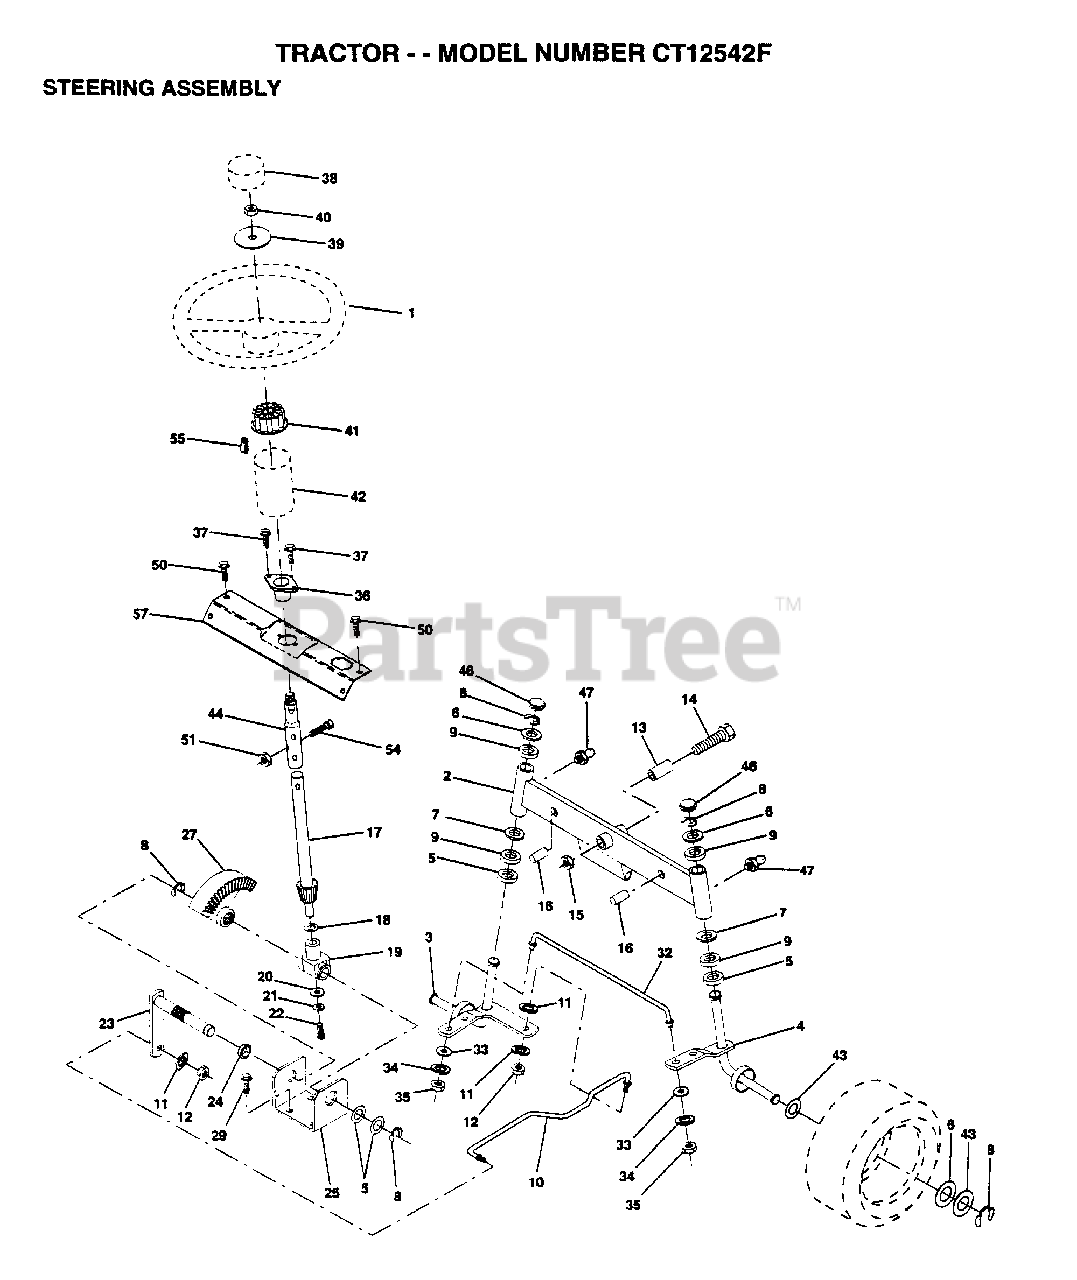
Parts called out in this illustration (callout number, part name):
1	WHEEL STR AYP BLK
2	AXLE ASM FRONT
3	SPINDLE LH
4	SPINDLE RH
5	WASHER .T
6	WASHER
7	WASHER
8	RING
9	COL. SRTG. BEAR.
11	LOCKWASHER
13	BEARING
14	BOLT HEX 5/8-11
15	"NUT-LOC,FLANGE LT"
16	AXLE PIN
17	SHAFT ASM STEERIN
18	THRUST WASHER
19	SUPPORT.SHAFT
21	LOCKWASHER
22	"SCREW,SPECIAL"
24	NYLINER T
25	"BRKT,STEERING"
27	GEAR SECTOR
29	SCREW
32	ROD.TIE.19.75
33	WASHER M
34	LOCKWASHER
35	NUT.LOCK.5/16-24
38	CAP STEER AYP
39	WASHER T
40	GRIPCO NUT
41	ADAPTER-WHEEL LT
42	BOOT SHAFT STEER
43	WASHER
44	SHAFT EXT STEER
46	CAP
47	ZERK M
50	SCREW HEX CRT
51	NUT
54	BOLT
55	CLIP TINNERMAN
57	SUPPORT SHAFT STR
